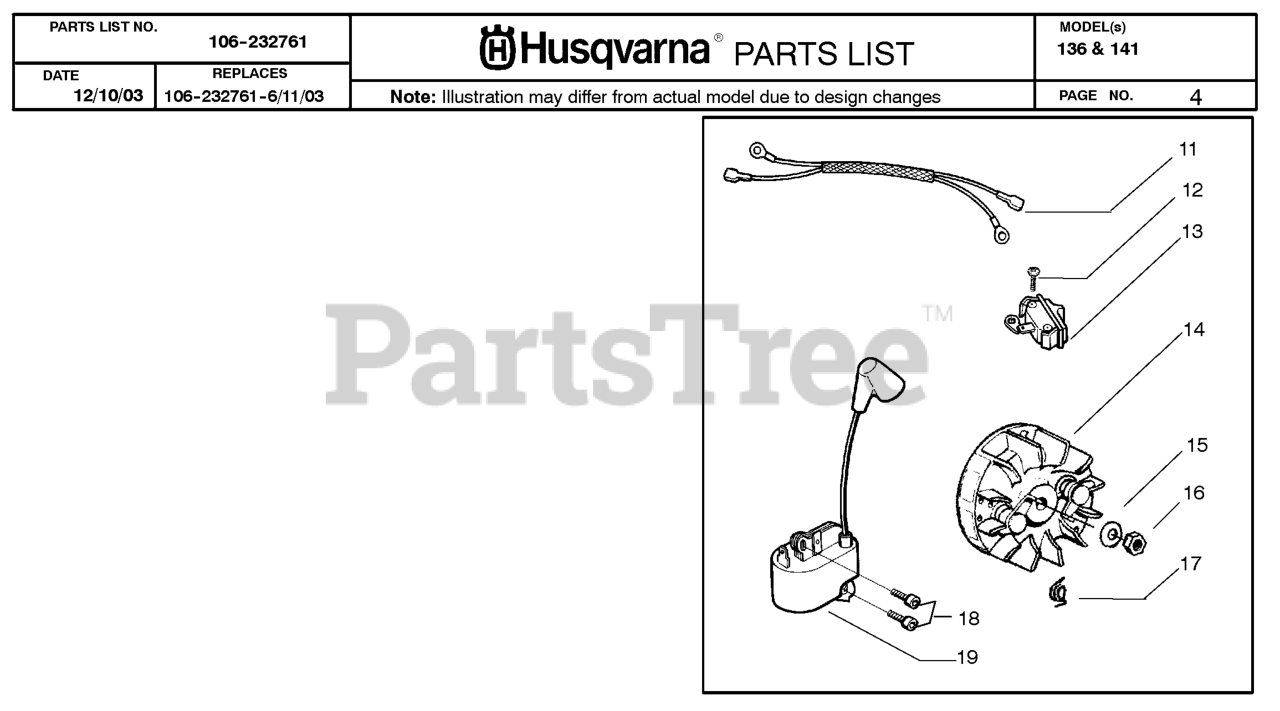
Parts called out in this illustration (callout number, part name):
11	LEAD WIRE ASSY
13	SWITCH ON/OFF
14	ROTOR COMPL. 36/41
15	WASHER-FLYWHEEL
17	SPRING STR DOG
18	SCREW,IGN MOD 36/41
19	%IGNITION MODULE
